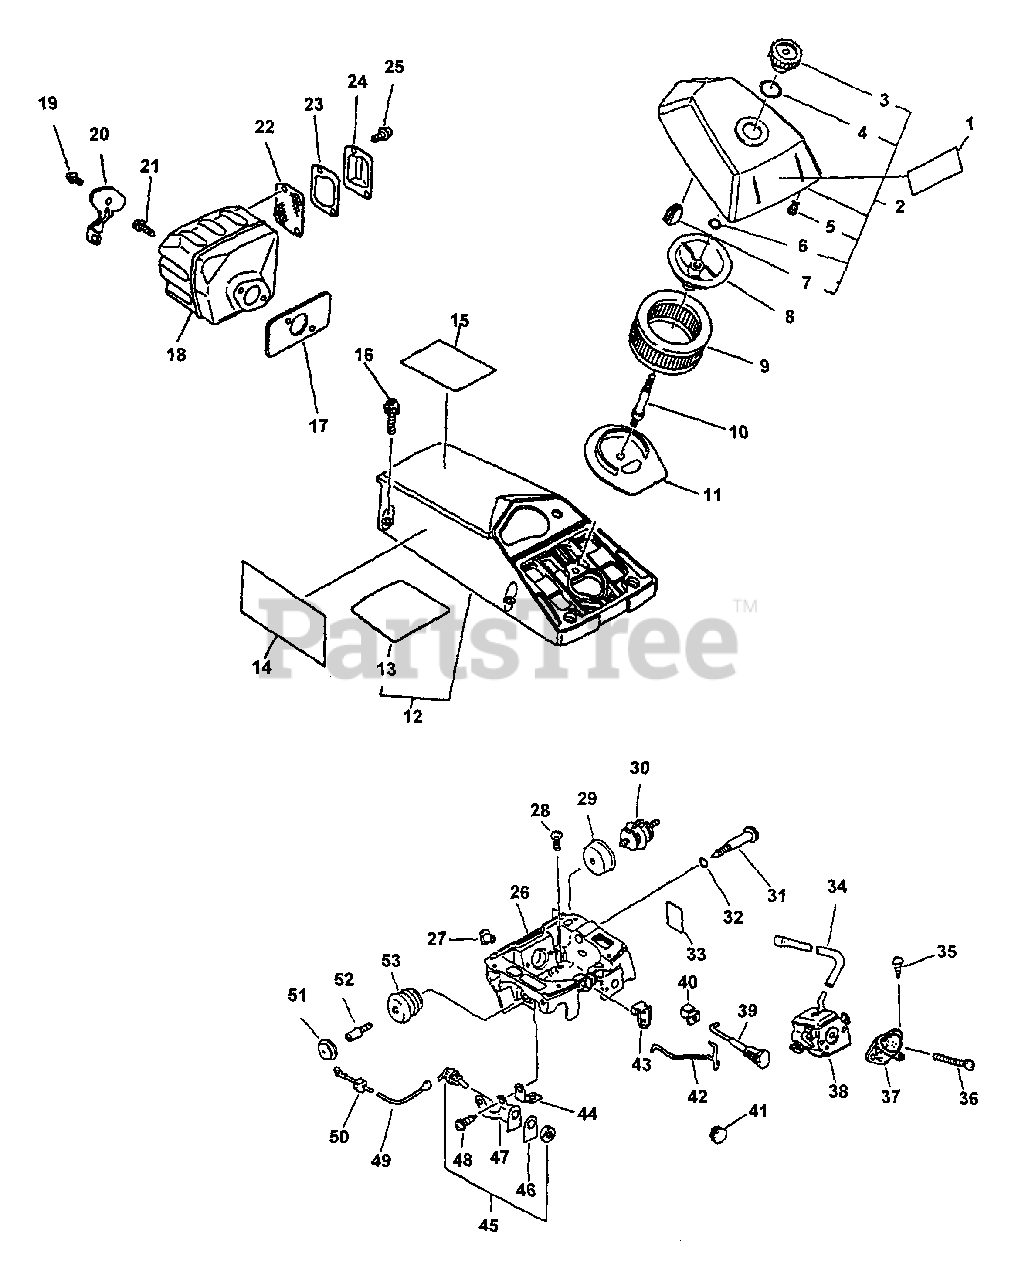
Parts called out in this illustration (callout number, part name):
1	LABEL - MODEL
2	AIR FILTER COVER ASSY
3	THUMBNUT
4	O-RING - 21
6	O-RING - 11
8	BRACKET, AIR CLEANER
9	FILTER, AIR
10	STUD
11	BRACKET, AIR CLEANER
12	COVER, ENGINE
13	COVER, ENGINE
14	LABEL - BAR & CHAIN
15	LABEL - KICK BACK
16	SCREW - 5X18
17	GASKET, EXHAUST
18	MUFFLER
19	SCREW - 5X10
20	BRACKET, MUFFLER
21	SCREW - 5X20
22	SCREEN, SPARK ARRESTOR
23	GASKET, EXHAUST
24	LID, MUFFLER
25	SCREW - 4X10
26	CASE, CARBURETOR
28	SCREW - 5X18
29	PLATE, CUSHION
30	CUSHION
31	KNOB, CARBURETOR ADJUST
32	O-RING - 6
33	LABEL - IDLE
34	PIPE - IMPULSE
35	SCREW - 5X14
36	SCREW - 5X50
37	ADAPTOR, INTAKE
38	CARBURETOR HDA-145A
39	ROD, CHOKE
40	GROMMET
42	ROD, THROTTLE
43	GUIDE, THROTTLE ROD
44	TERMINAL - GROUND
45	IGNITION SWITCH ASSY
46	LABEL - SWITCH
47	BRACKET, SWITCH
48	SCREW - 5X10
49	LEAD - GROUND
51	CAP, CUSHION
53	CUSHION
